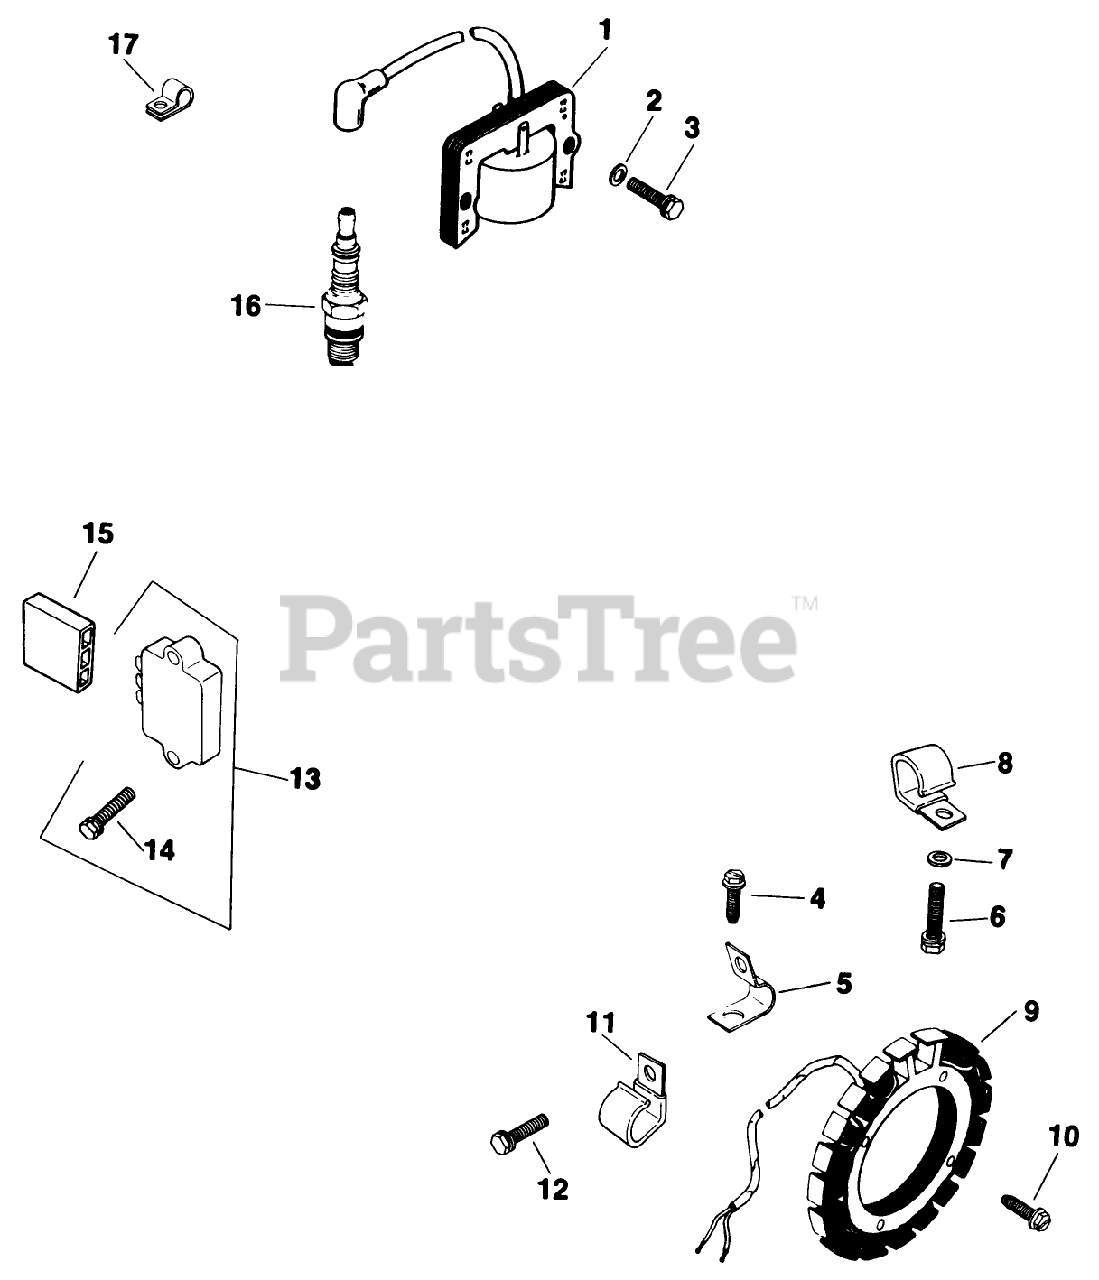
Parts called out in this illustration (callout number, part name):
1	KOHLER 47-584-02
2	KOHLER X-25-79
3	KOHLER X-156-1
4	KOHLER X-67-59
5	KOHLER X-728-1
8	Clip
9	KOHLER 237878
10	KOHLER X-67-51
11	Clip
13	KOHLER 41-403-05
14	KOHLER X-132-4
15	KOHLER 236602
16	KOHLER 235041-5
17	KOHLER 210281
